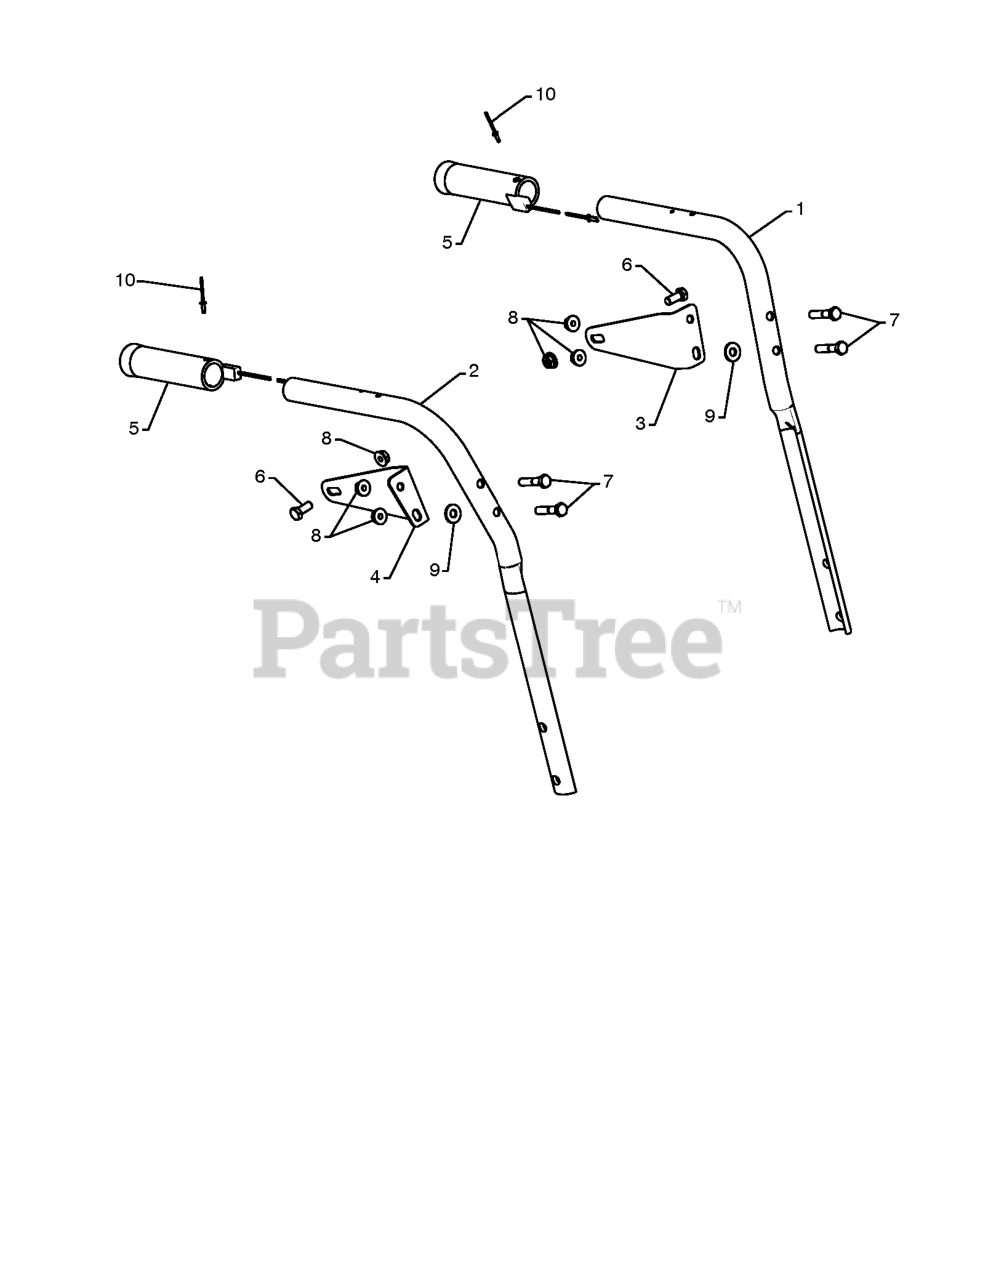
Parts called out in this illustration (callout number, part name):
1	TUBE.HANDLE.PLOW.LH.GREY
2	TUBE.HANDLE.PLOW.RH.GREY
3	BRKT.PANEL.LH.INT
4	BRKT.PANEL.RH.INT
5	GRIP.HANDLE.HEATED
6	BOLT.FIN.HEX.5/16-18X3/4
7	HEX BOLT
8	NUT.LOCK.5/16-18
9	WASHER.20X8.5
10	RIVET.POP.1/8X
